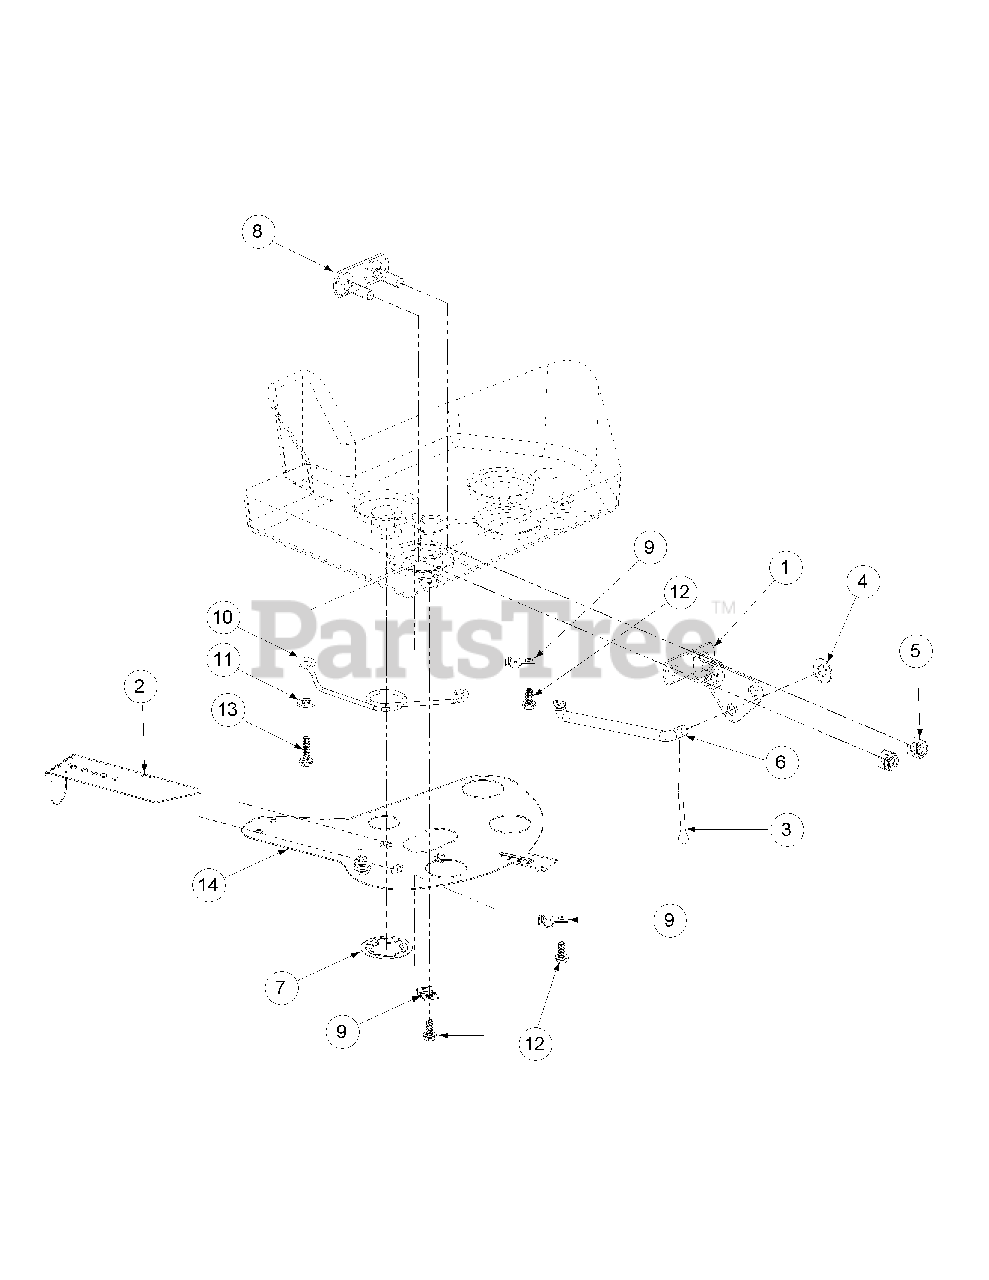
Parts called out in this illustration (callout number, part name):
1	Pivot Lever Assembly
2	Slide Lever
3	Cotter Pin, 3/32 x 1/2 Lg, SS
4	Flat Washer, 1/4"
5	Nylock Nut, 1/4-20
6	Pivot Lever Rod
7	Spring Clip
8	Two Hole Weldment Plate
9	Plate Shut-off Clip
10	Plate Shut-off Spring
11	Flat Washer
12	Index Washer Hex Screw, 8 x 3/8
13	Index Washer Hex Screw, 8 x 5/8
14	Shut-off Plate
